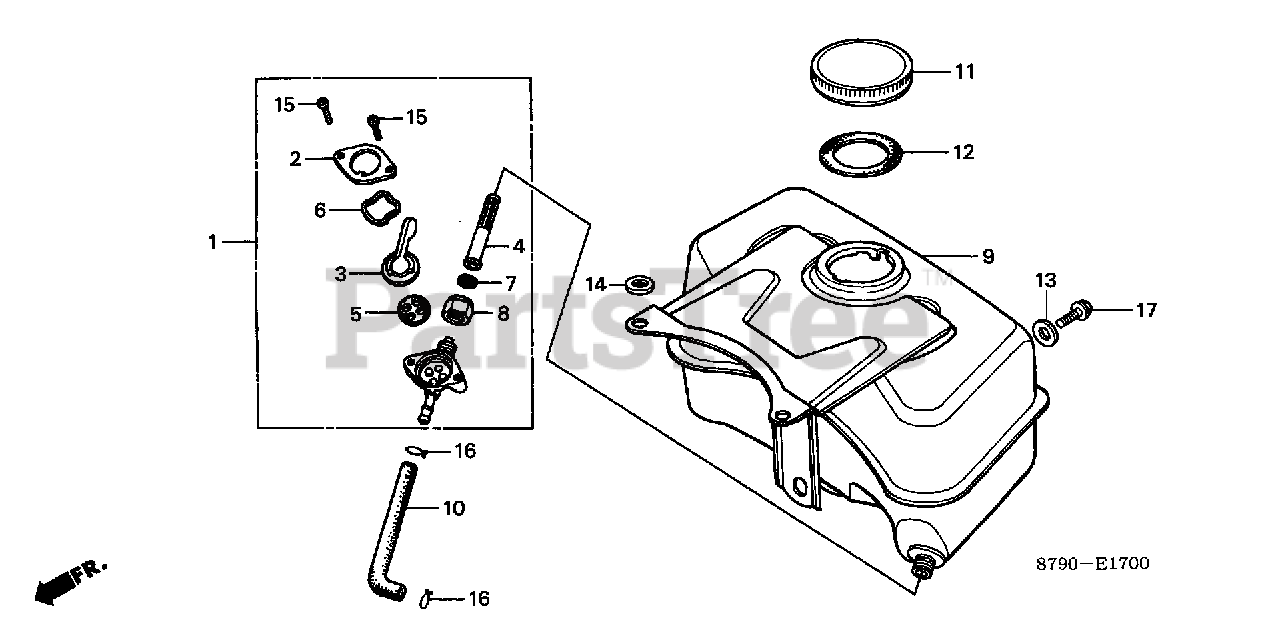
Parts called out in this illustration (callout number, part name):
1	PETCOCK ASSY. (NOT AVAILABLE)
2	COVER, PETCOCK (NOT AVAILABLE)
3	LEVER, PETCOCK (NOT AVAILABLE)
4	SCREEN, STRAINER
5	GASKET, PETCOCK VALVE
6	SPRING, PETCOCK LEVER
7	GASKET, FUEL STRAINER CUP
8	NUT, TURN BUCKLE (NOT AVAILABLE)
10	TUBE, FUEL
11	CAP, FUEL FILLER
11	CAP, SUB-TANK
12	GASKET, FUEL FILLER CAP
13	WASHER (6MM)
13	WASHER, WHEEL (6MM)
14	WASHER (6MM)
15	SCREW, PAN (3X6)
16	CLIP, TUBE (B8)
17	BOLT, FLANGE (6X10)
